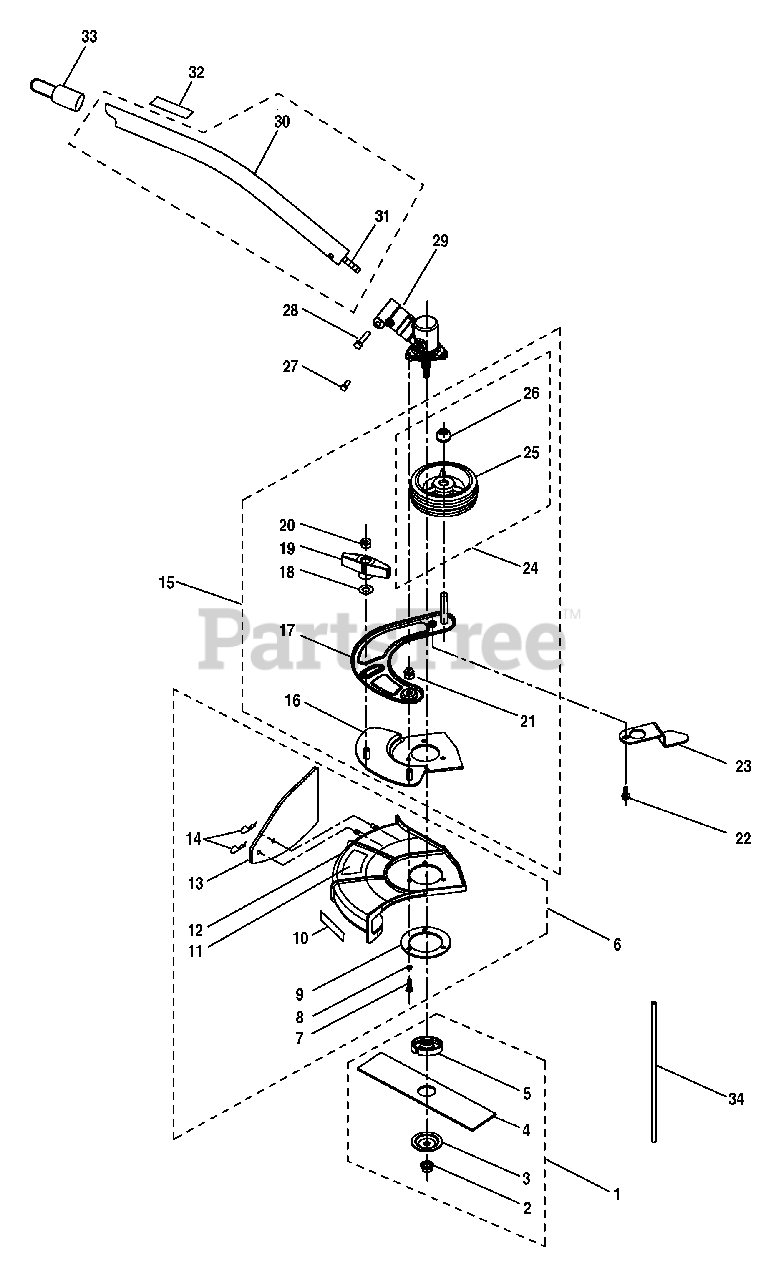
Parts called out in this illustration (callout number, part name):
1	BLADE ASSEMBLY
2	LOCK NUT (M8)
3	CUPPED WASHER
4	BLADE
5	FLANGED WASHER
6	BLADE GUARD ASSEMBLY
7	HEX SCREW (M5)
8	HELICAL LOCK WASHER (5 mm)
10	WARNING DECAL
11	EXPAND-IT LOGO LABEL
12	BLADE GUARD
13	DRAG FLAP
14	PUSH CLIP
15	SUPPORT ARM ASSEMBLY (UT15518B)
16	PLATE WITH STUD
17	SUPPORT ARM
18	WASHER (10 mm)
19	ADJUSTING KNOB
20	HEX NUT
21	HEX NUT W/NYLON CAP
22	SCREW (10-24 x 1/2 in. HEX HD.)
23	CURB GUIDE
24	WHEEL ASSEMBLY
25	WHEEL
26	PUSH NUT (10 mm)
27	HEX SCREW (10-24 x 5/8 in. PAN HD.)
28	SCREW (1/4-20 x 1-1/4 in. PAN HD.)
29	GEAR HEAD ASSEMBLY
30	DRIVE SHAFT ASSEMBLY
31	FLEX SHAFT
32	WARNING DECAL
33	HANGER CAP
34	HOLDING PIN
